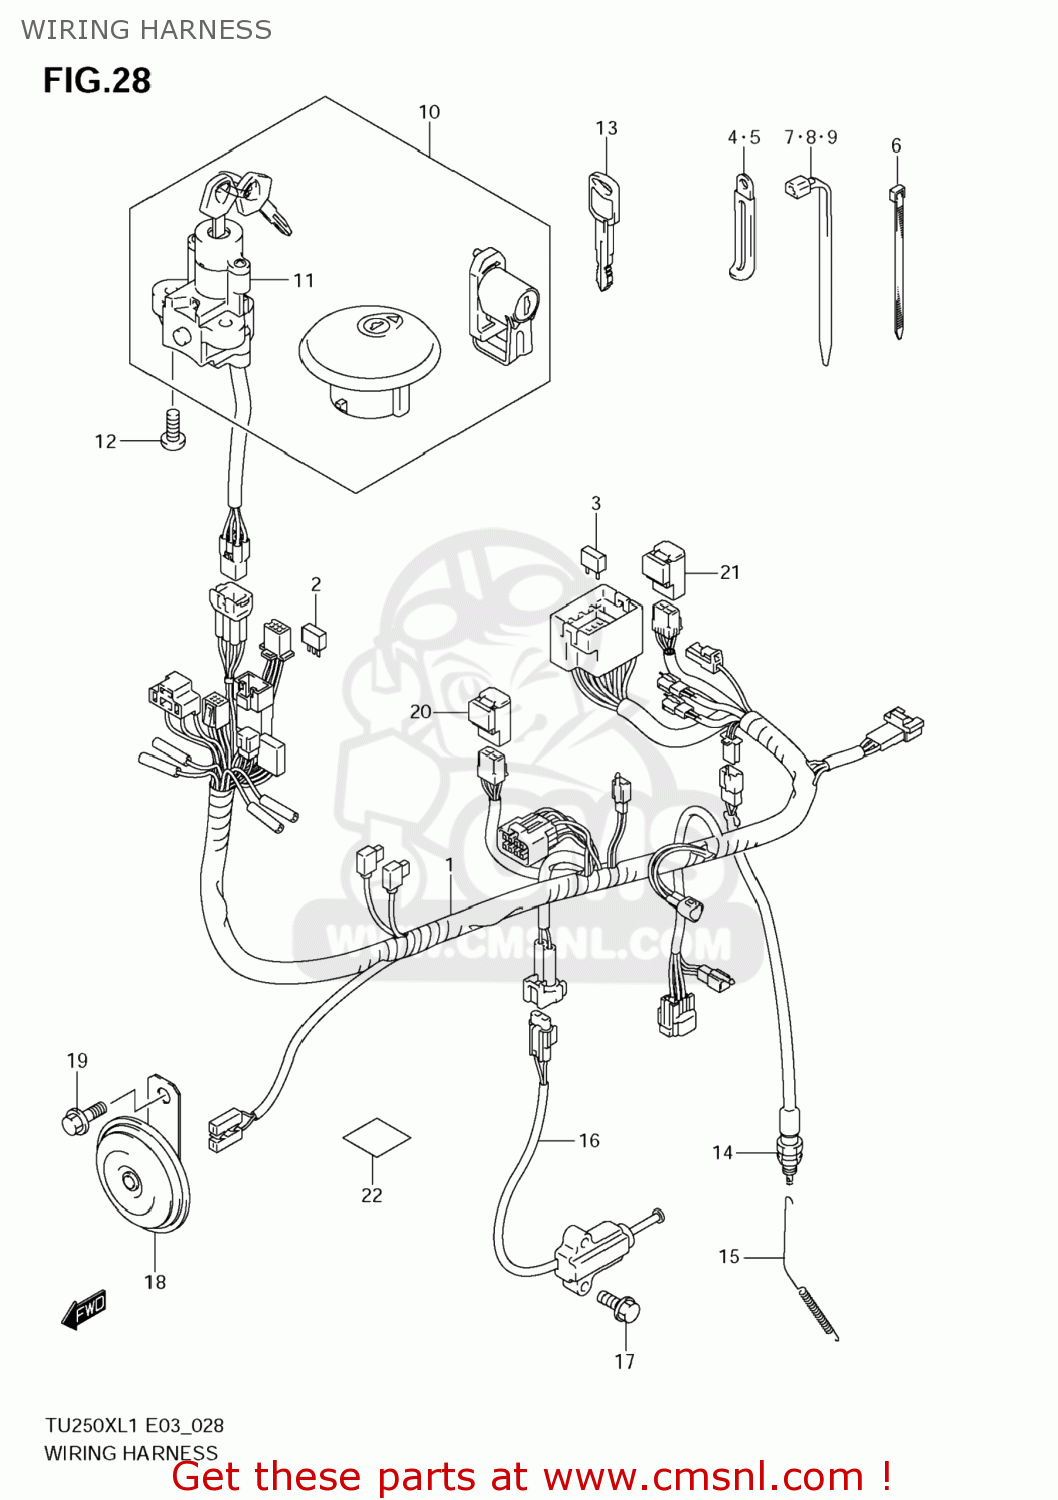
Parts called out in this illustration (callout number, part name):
1	HARNESS,WIRING
2	DIODE(STANLEY DE8804)
3	FUSE(10A)
4	CLAMP(L:80)
5	CLAMP(L:80)
6	CLAMP(L:95)
7	CLAMP(L:95)
8	CLAMP(L:125)
9	CLAMP(L:190)
10	LOCK SET
11	LOCK ASSY,STEERING
12	BOLT(8X20)
13	KEY,BLANK
14	SWITCH ASSY,STOP LAMP
15	SPRING
16	SWITCH ASSY,SIDE STAND
17	BOLT
18	HORN ASSY
19	BOLT
20	RELAY ASSY
21	RELAY ASSY
22	PROTECTOR,WIRING HARNESS
